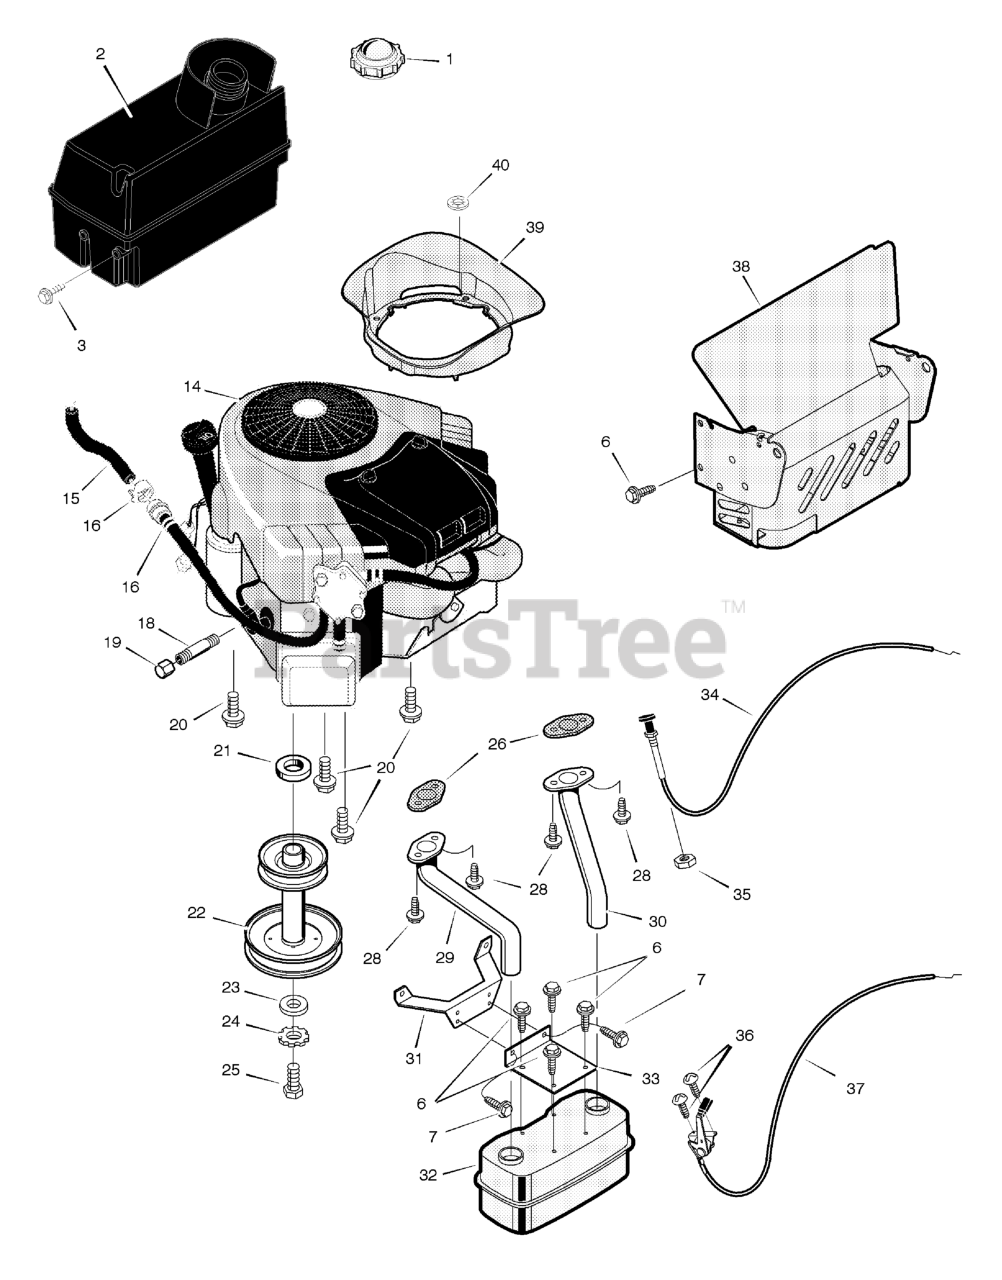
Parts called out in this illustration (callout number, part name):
1	Cap, Fuel
2	Tank, Fuel
14	Engine *
15	Fuel Line (Must cut to length)
16	Clamp
18	Pipe, Oil Drain
19	Cap, Oil Drain
20	Bolt
22	Pulley, Stack
24	Lockwasher
27	Washer
29	Tube, Right Exhaust
30	Tube, Left Exhaust
31	Bracket, Muffler Mount
32	Muffler
33	Bracket, Muffler
35	Nut
37	Control, Throttle
38	Shield Assembly, Heat
40	Nut, Speed
